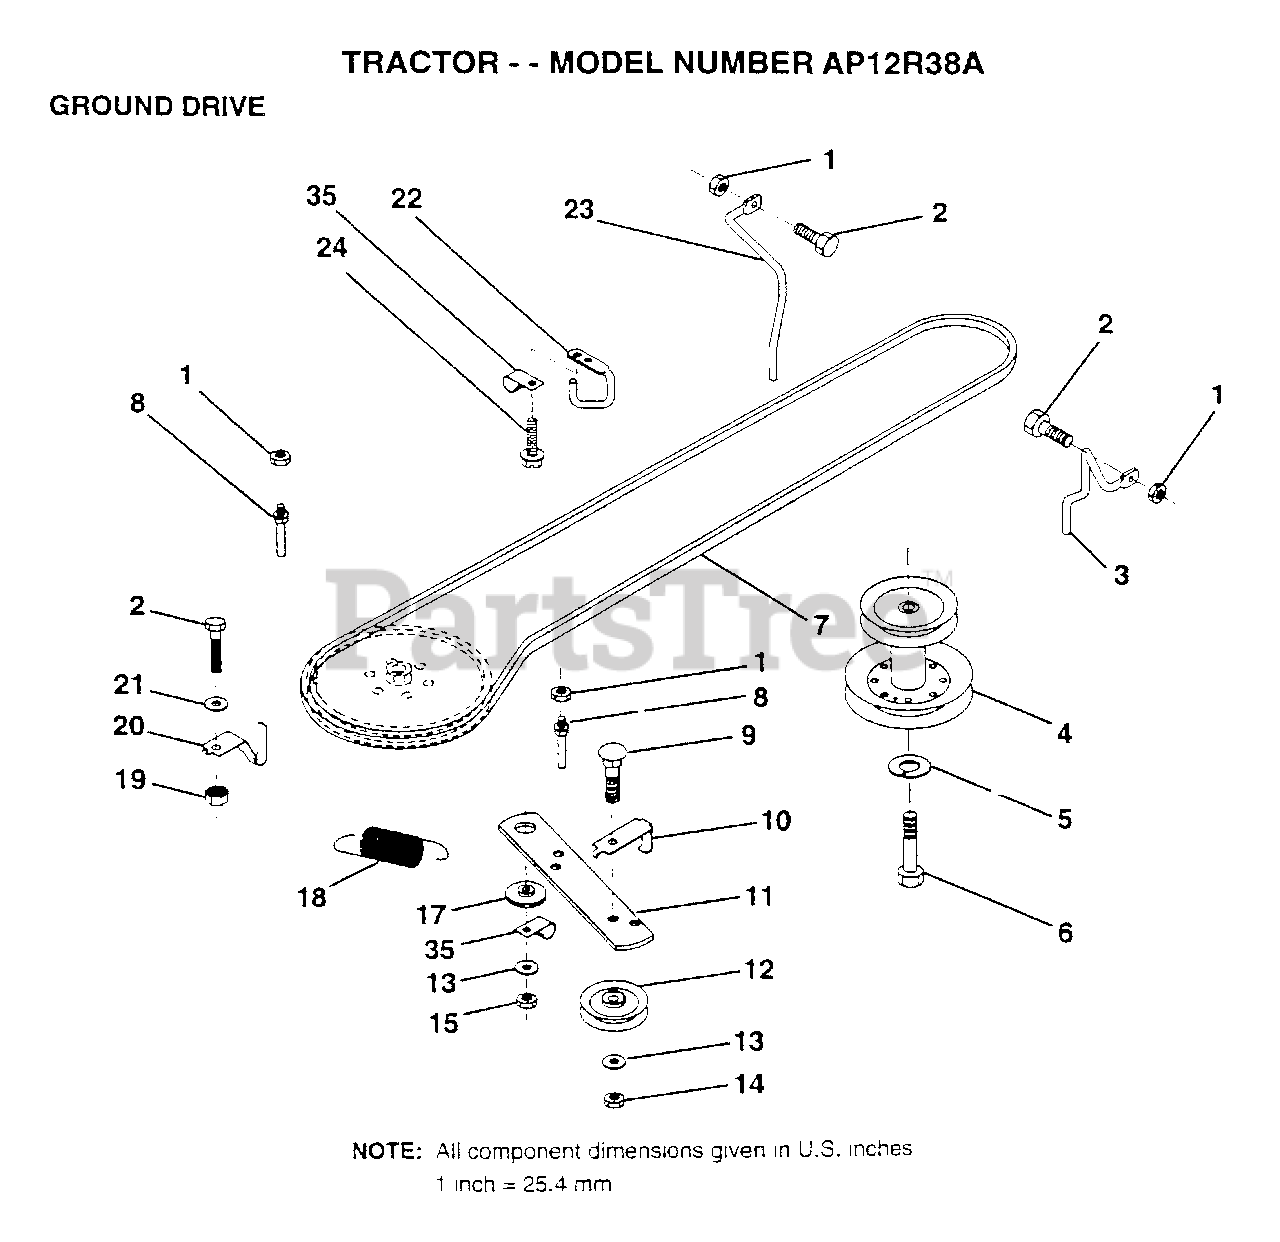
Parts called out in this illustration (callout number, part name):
2	BOLT
3	KEEPER.BELT.FRT.
4	PULLEY.ENGINE.LR
5	LOCKWASHER
6	HEX BOLT
7	BELT
8	"KEEPER,DRIVE BELT"
9	BOLT
10	"KEEP,IDLER DR BEL"
11	ARM IDLER CLUT GD
12	PULLEY.IDLER.FLAT
13	WASHER
14	LOCKNUT
17	SPACER RETAINER
20	KEEPER.BELT.T/A
21	WASHER
22	"KEEPER,FRA DR BEL"
23	KEEPER.BELT.FRT.L
24	SCREW
35	CLIP INSULATOR
